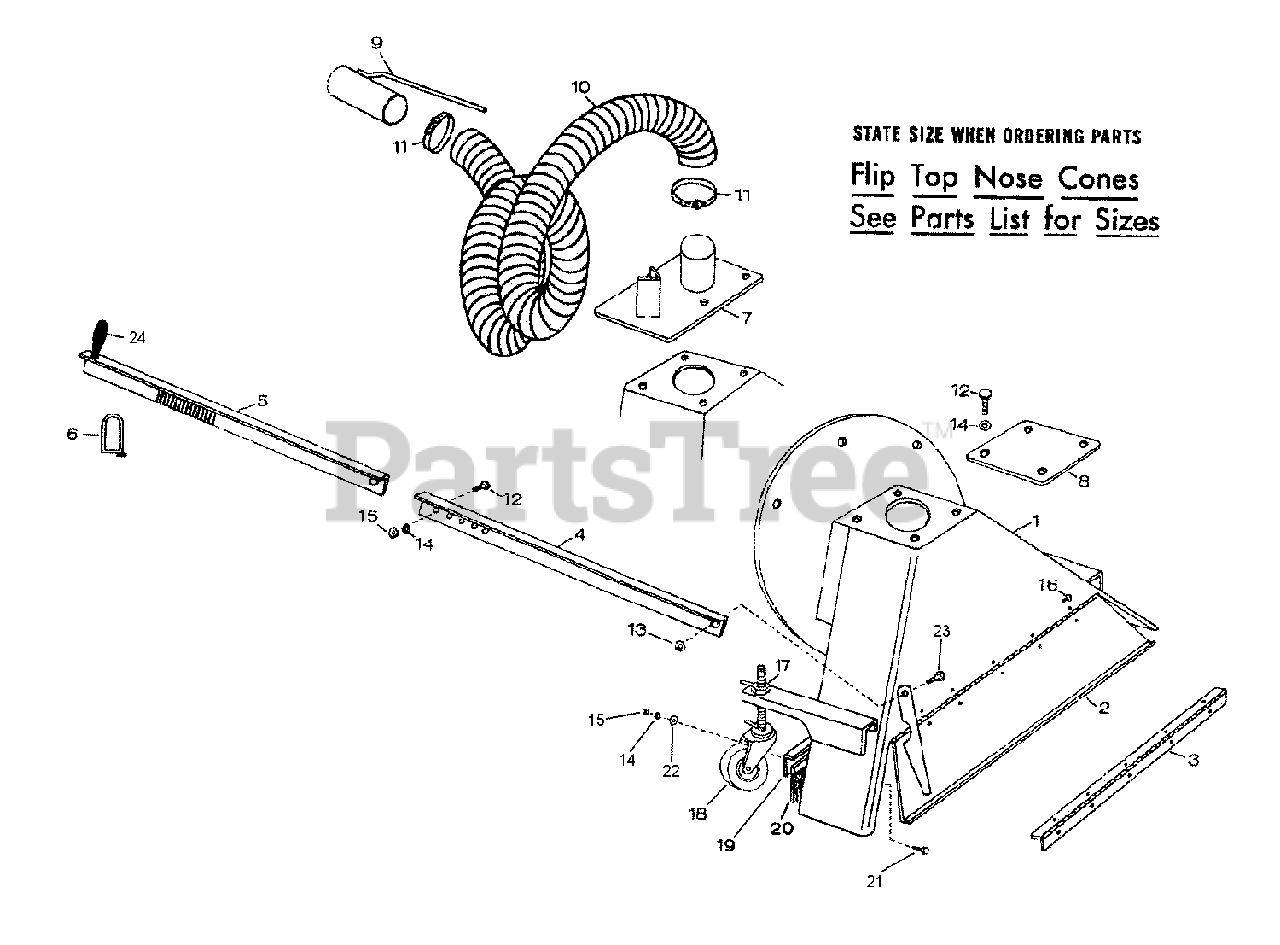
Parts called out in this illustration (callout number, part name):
1	FT30 nose cone body
1	FT36 nose cone body
2	Door FT30
2	Door FT36
3	Hinge FT30
3	Hinge FT36
4	Lower adjuster bar
5	Upper adjuster bar
6	Nut, U-clip – w/5/16-18
7	Intake flange and holder 4"
7	Intake flange and holder 5"
7	Intake flange 4"
7	Intake flange 5"
7	Intake flange 6"
7	Intake flange 8"
8	Cover plate
9	Intake nozzle 4"
9	Intake nozzle 5"
9	Intake nozzle 6"
9	Intake nozzle 8"
10	Intake hose 4"
10	Intake hose 5"
11	Hose clamp 4"
11	Hose clamp 5"
12	Bolt, 5/16 x 3/4" hex
13	Nut, 5/16" lock
14	Washer, 5/16" lock
15	Nut, 5/16" hex
16	Rivit, 3/16"
17	Nut, 3/4" wing
18	4" caster wheel
19	30" brush holder
19	36" brush holder
20	30" brush
20	36" brush
21	Bolt, 5/16-18 x 1-1/4 hex
22	Washer, 5/16 flat
23	Bolt, 5/16 x 5/8" hex
24	Grip, Handle 1 x 4"
